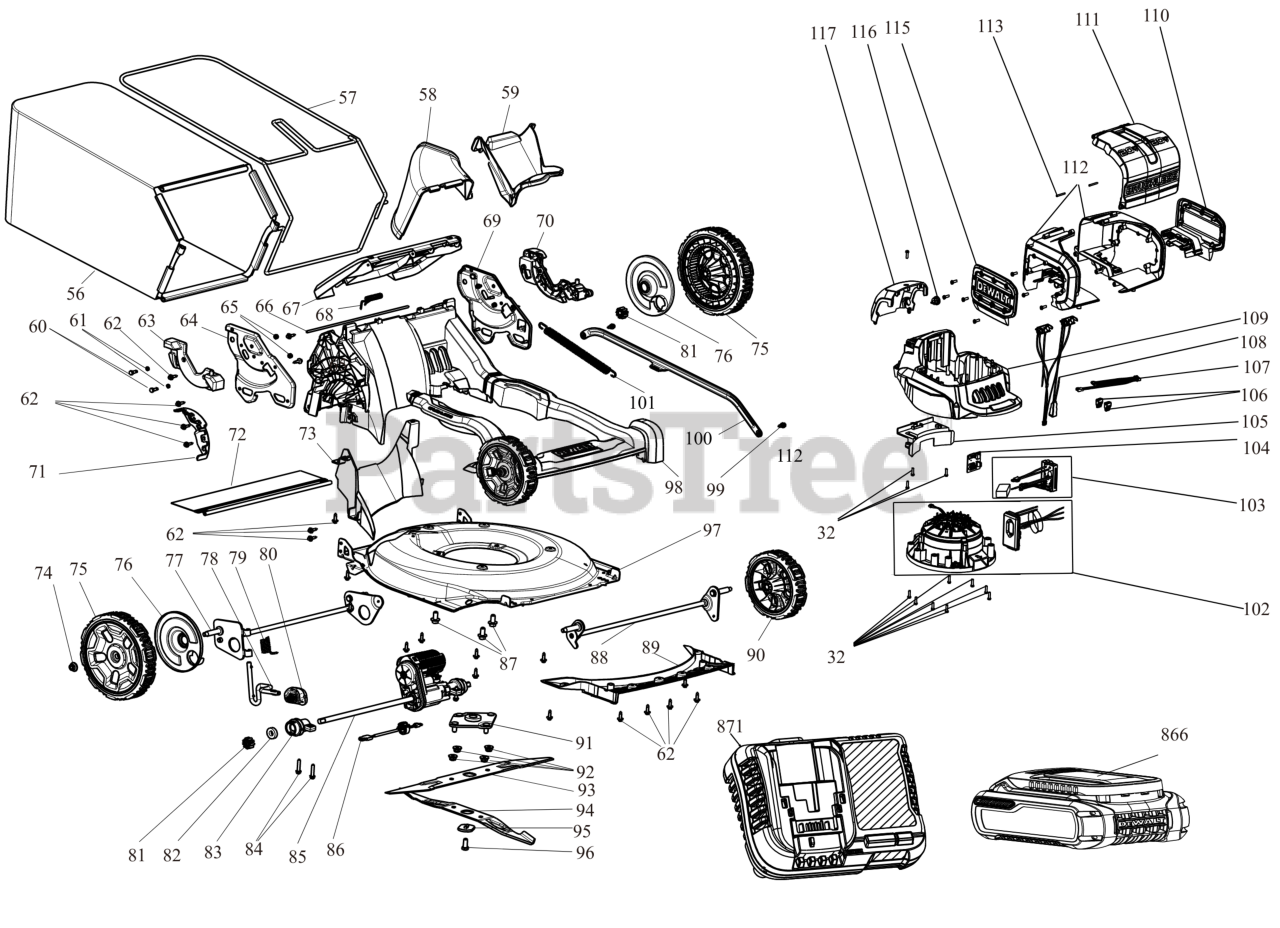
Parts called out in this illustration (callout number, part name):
1	BUTTON
2	SPRING
3	SCREW
5	COVER
6	POTENTIOMETER SA
7	CONTROL
9	BUTTOM
10	HANDLE
11	WIRE HARNESS
12	SWITCH
13	WIRE HARNESS
15	SCREW M6X45-T30-THD FRM
16	SWITCHBOX
18	HOUSING SA
19	CATCH
21	SPRING TORSION
22	WIRE HARNESS
23	PADDLE
24	PADDLE
25	PIVOT
26	COVER
27	STRIP
28	SLEEVE
29	TUBE UPPER
31	TUBE LOWER
32	SCREW M4.55X16 T20-PLAS THD FRM
33	SLEEVE
35	WASHER
36	SCREW
39	SPRING
41	SPRING
42	SPRING
43	COVER
46	SPRING
49	HOLDER
50	HARNESS
51	COVER
52	BUTTON
53	COVER
55	CORE
56	GRASSBAG
57	FRAME
58	CHUTE
61	SPACER
62	SCREW 1/4-10 x .750
63	SUPPORT
64	BRACKET
65	LOCK-NUT
68	SPRING
69	BRACKET
70	SUPPORT
71	BRACKET
72	SHIELD
73	INSERT
74	FLANGE LOCK NUT
75	WHEELS
76	COVER LH
77	AXLE REAR
79	SPRING
82	BEARING
83	HOLDER
84	SCREW
85	TRANSMISSON SA
86	HARNESS
88	AXLE FRONT
90	WHEELS
91	PLATE
93	BLADE MOUNT
94	BLADE MOUNT
95	WASHER
97	PLATE
101	SPRING
102	MOTOR SA
103	MODULE
104	PCB SA
105	BAFFLE
106	CONNECTOR
107	HARNESS
108	WIRE HARNESS
109	COVER
110	PLATE SA
112	HOUSING SA
115	COVER SA
116	BUSHING
117	COVER
118	SA HANDLE PNL KIT RWD-YELLOW
119	LABEL
866	20V BATTERY MAX XR 10AH DCB210
871	CHARGER
